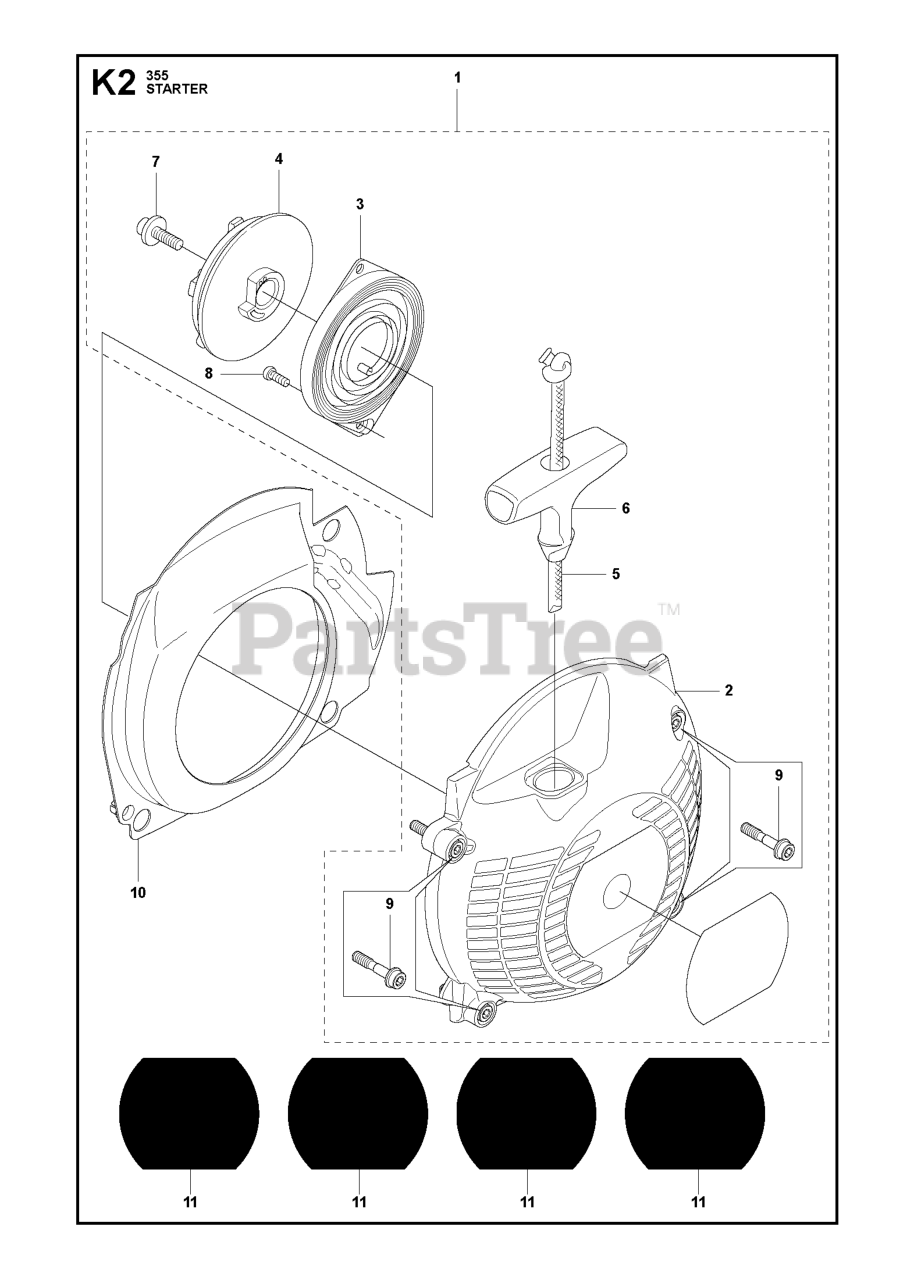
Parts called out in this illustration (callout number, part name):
1	STARTER ASSY
2	STARTER HOUSING SPARE PART IN
3	RECOIL SPRING
4	STARTER PULLEY
5	STARTER ROPE
9	SCREW IHSCFMO
10	AIR CONDUCTOR
11	LABEL
